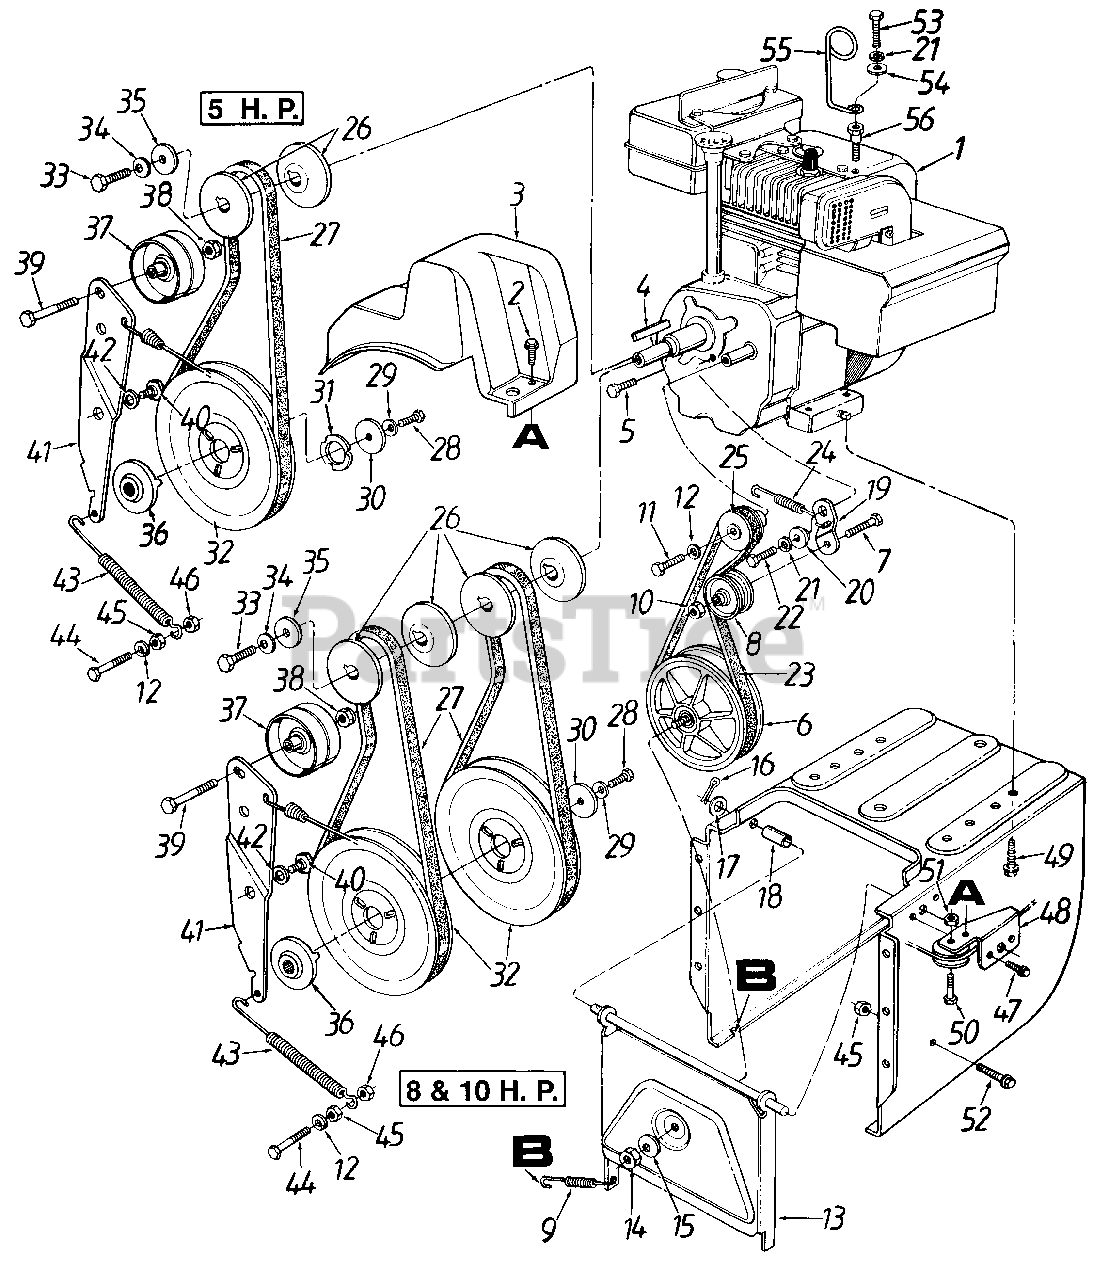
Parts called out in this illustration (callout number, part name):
1	Engine
2	Hex Wash. Hd. TT-Tap Scr. 1/4-20 x .5" Lg.
3	Belt Cover
4	Sq.-Key 3/16 x 1.5" Lg.
5	Hex Patch Bolt 5/16-24 x 1" Lg. (Gr. 5)
6	Friction Wheel Disc Ass'y.
7	Hex Bolt 3/8-16 x 1.25" Lg.
8	Fl-Idler 2.12" O.D.
9	Ext. Spring 2.5" Lg.
10	Hex Top L-Nut 3/8-16 Thd.
11	Hex Bolt 1/4-28 x .5" Lg.
12	L-Wash. 1/4" I.D.
15	Bell-Wash. .38" I.D. x .88" O.D.
16	Cotter Pin 1/8" x .75" Lg.
17	Fl-Wash. .531" I.D. x .93" O.D.
18	Spacer .508" I.D. x .75" O.D.
19	Drive Clutch Idler Bracket
20	Shld. Spacer .5" Dia. x .27" Lg.
21	L-Wash. 5/16" I.D.
22	Hex Bolt 5/16-24 x 1" Lg.
23	"V"-Belt
24	Extension Spring
25	2" Dia. Pulley
26	3/8 "V"-Pulley Half
27	"V"-Belt
28	Hex Cap L-Bolt 5/16-24 x .75" Lg.
29	Bell-Wash. .345" I.D. x .88" O.D.
30	Fl-Wash. .34" I.D. x 1.5" O.D.
31	Brg. Retaining Washer
32	Auger Pulley
33	Hex Bolt 3/8-24 x .88" Lg.
34	Bell-Wash. .39" I.D. x 1.13" O.D.
35	Fl-Wash. .406" 1. D. x 1.25" O.D.
36	Adapter Pulley
37	Fl-idler 2.75" O.D.
38	Hex Ins. L-Nut 3/8-24 Thd.
39	Hex Bolt 3/8-24 x 1.5" Lg. (Gr. 5)
40	Shld. Bolt .625" Dia. x .170" Lg.
42	Wave Wash. .66" I.D. x .88"
43	Ext. Spring 3.6" Lg.
44	Hex Bolt 1/4-20 x .75" Lg.
45	Hex Nut 1/4-20 Thd.
46	Hex L-Nut 1/4-20 Thd.
47	Torx Mach. AB-Tap Scr. 1/4 x .62" Lg.
50	Shld. Bolt 5/16" Dia. x .35" Lg.
51	Hex Jam Nut 1/4-20 Thd.
52	Hex Wash. Hd. TT-Tap Scr. 1/4-20 x 1" Lg.
53	Hex Bolt 5/16-18 x 5/8" Lg.
54	Fl-Wash. .349" I.D. x .879" O.D.
55	Cable Control Wire
56	Engine Stud
